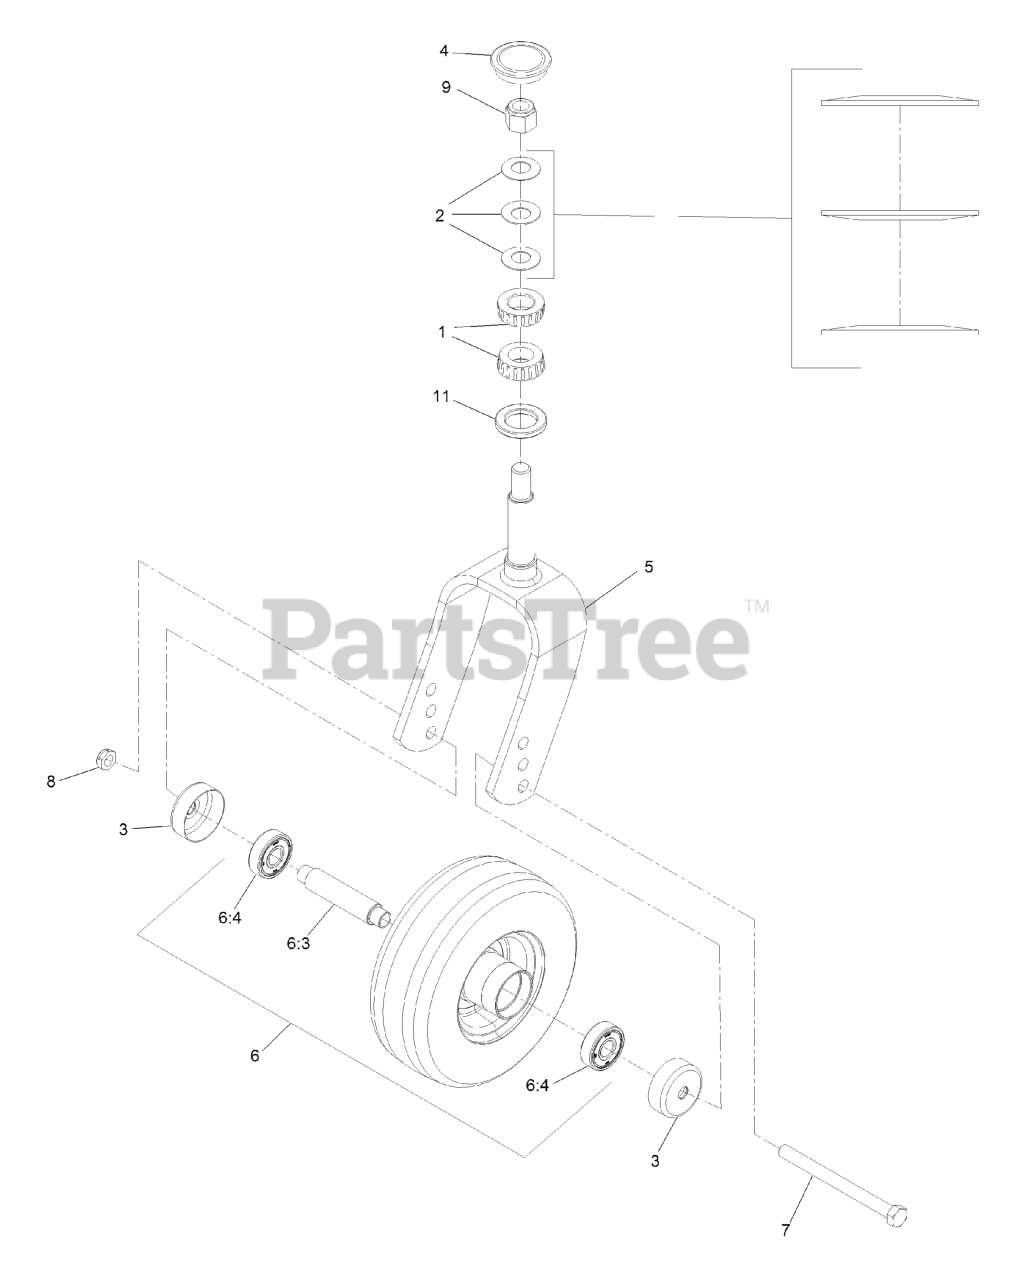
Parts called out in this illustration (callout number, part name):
1	Cone-Bearing Tapered Roller
2	WASHER-BELLVILLE
3	GUARD, SEAL
4	CAP-GREASE
5	FORK-CASTER 9"
6	WHEEL AND TIRE ASM
6:3	AXLE-CASTER
6:4	BEARING
7	SCREW-HH
8	NUT-HEX
9	NUT-LOCK, NI
11	SEAL-GREASE
